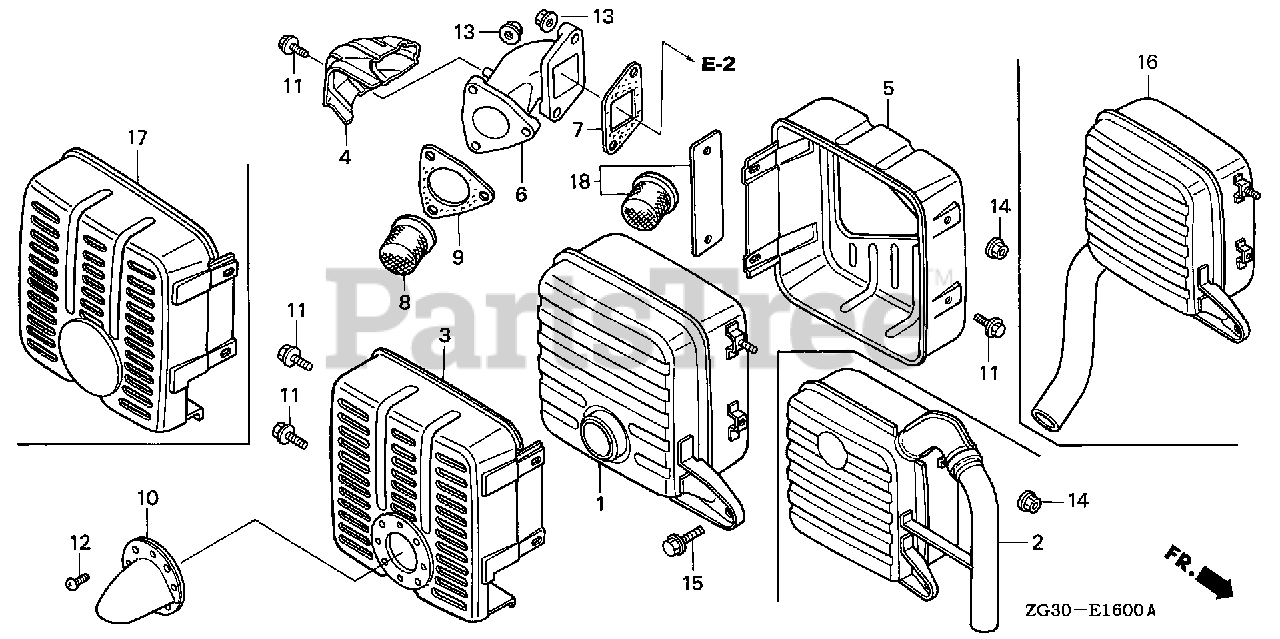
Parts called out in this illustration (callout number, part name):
3	PROTECTOR A, MUFFLER
4	PROTECTOR, EX. PIPE (NOT AVAILABLE)
5	PROTECTOR B, MUFFLER
6	PIPE, EX.
7	GASKET, EX. PIPE (NON-ASBESTOS)
8	ARRESTER, SPARK
9	GASKET, MUFFLER (NON-ASBESTOS)
10	DEFLECTOR, MUFFLER
11	BOLT, FLANGE (5X8)
12	SCREW, PAN (5X8)
13	NUT, FLANGE (8MM)
14	NUT, FLANGE (8MM)
15	BOLT, FLANGE (8X20)
